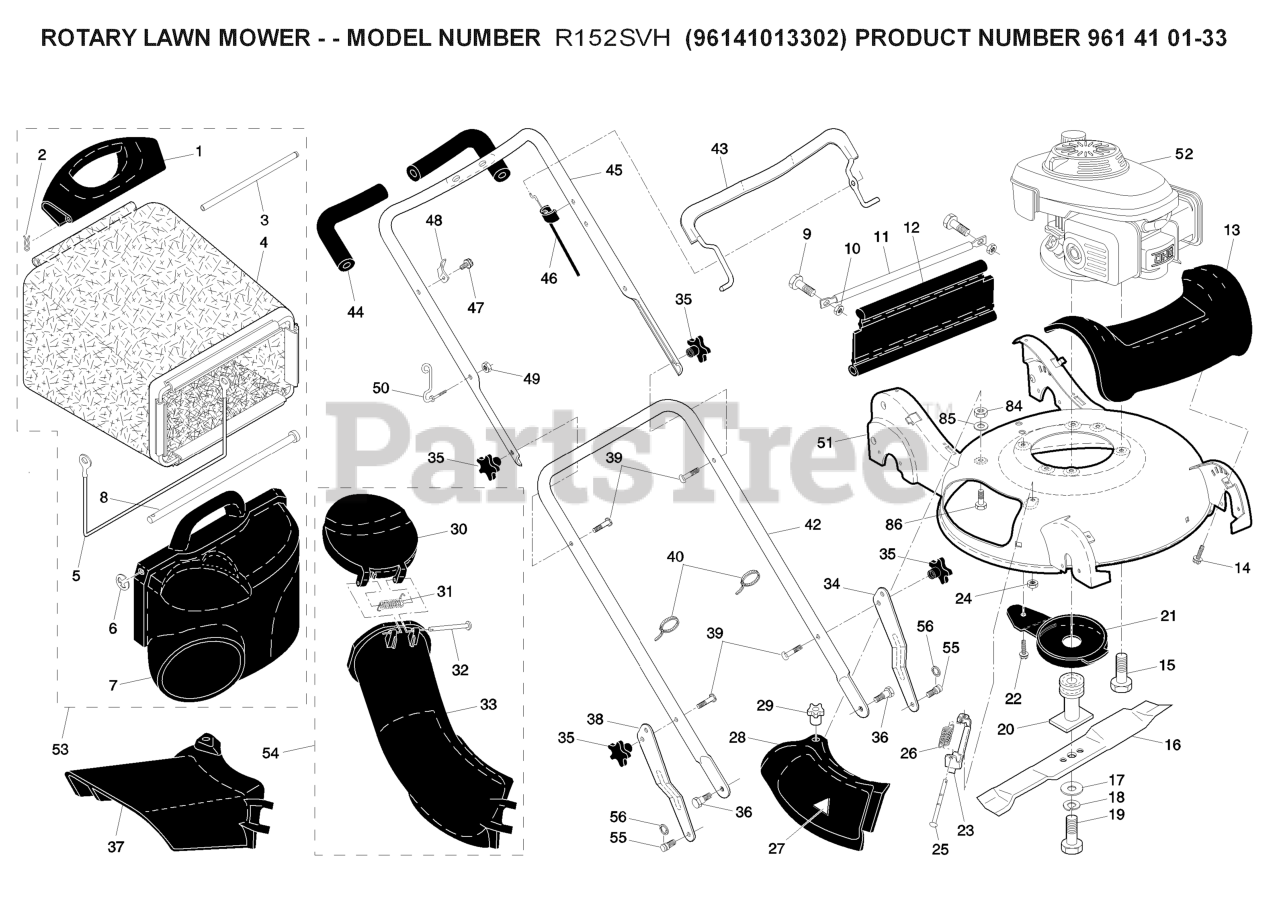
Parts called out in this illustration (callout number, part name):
1	HANDLE.GRASSBAG.REAR.H-GRAY
2	COTTER PIN (3 2)(2 2MC)
3	ROD.REAR.HANDLE.YELLOW
5	FRAME, GRASSBAG
7	DOOR, GRASSBAG
8	ROD, PIVOT
10	LOCKNUT.NYLOC.1/4-20
11	TUBE, REAR SKIRT
13	COVER.FRONT.21.HV.H-GRAY
14	SCREW, HEX WASHER HEAD
15	BOLT 3/8-16X1-1/8
16	Blade, 21"
17	WASHER,HARDEN
18	LOCKWASHER
19	BOLT.HD.HEAD.3/8-24X2.50 (2 2)
20	ADAPTER.BLADE
21	DEBRIS SHEILD
22	SCREW 1/4X20
23	BRACKET.ASM.HINGE
24	NUT.HEX.FLANGE.1/4
25	ROD.HINGE.1/4"3.82"
26	SPRING.MULCH.DOOR
27	DECAL.INTERNATIONL.CUTFINGER
28	MULCHER DOOR
29	KNOB.MULCH.DOOR
30	CHUTE.DOOR.21.HV.H-GRAY
32	ROD.HINGE.1/4"3.82"
33	DISCHARGE CHUTE PLASTIC
34	ADJUSTMENT BRACKET, LOWER LH
35	KNOB.HANDLE.STAR.HUSQ.GRAY
36	SCREW.5/16X.680.TRIM.H
37	GUARD.CLIP.ON.21.HV.GRAY
38	BRACKET.ADJ.LOWER.HDL.RT.GREY
39	BOLT, HANDLE 5/16-18X1.75
40	TIE GUIDE
42	HANDLE.LOWER.GREY
43	BAIL CONTROL
44	GRIP.HANDLE.FOAM.WIDE.(1 SIDE)
45	HANDLE.ASM.UPPER.W/GRIP
46	CABLE.MZR.50.SNAP-IN
48	BRACKET
49	NUT
50	GUIDE.ROPE.WALK.MOWER
53	Grassbag Assembly, Complete
54	CHUTE.LOWER.ASM.WALK.MOWER
55	STUD.SHOULDER.T45.BZP
56	E-RING 7/16 RE
84	NUT, HEX
85	LOCKWASHER
86	BOLT.CARRIAGE.1/4-20 X 7/8
